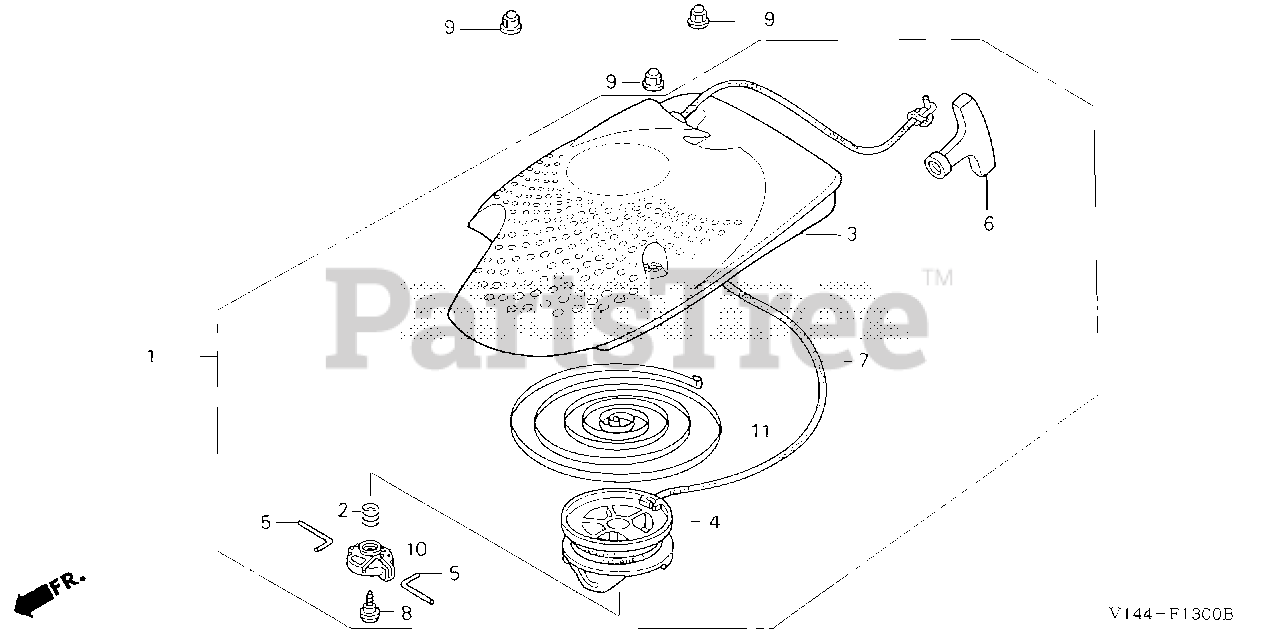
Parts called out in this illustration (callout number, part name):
1	STARTER ASSY., RECOIL *R280* (POWER RED)
2	SPRING, FRICTION
3	CASE, STARTER *R280* (POWER RED)
4	REEL, RECOIL STARTER
6	KNOB, RECOIL STARTER
6	GRIP, STARTER
7	ROPE, RECOIL STARTER
8	SCREW, SETTING
9	NUT, FLANGE CAP (5MM)
11	SPRING, RECOIL STARTER
